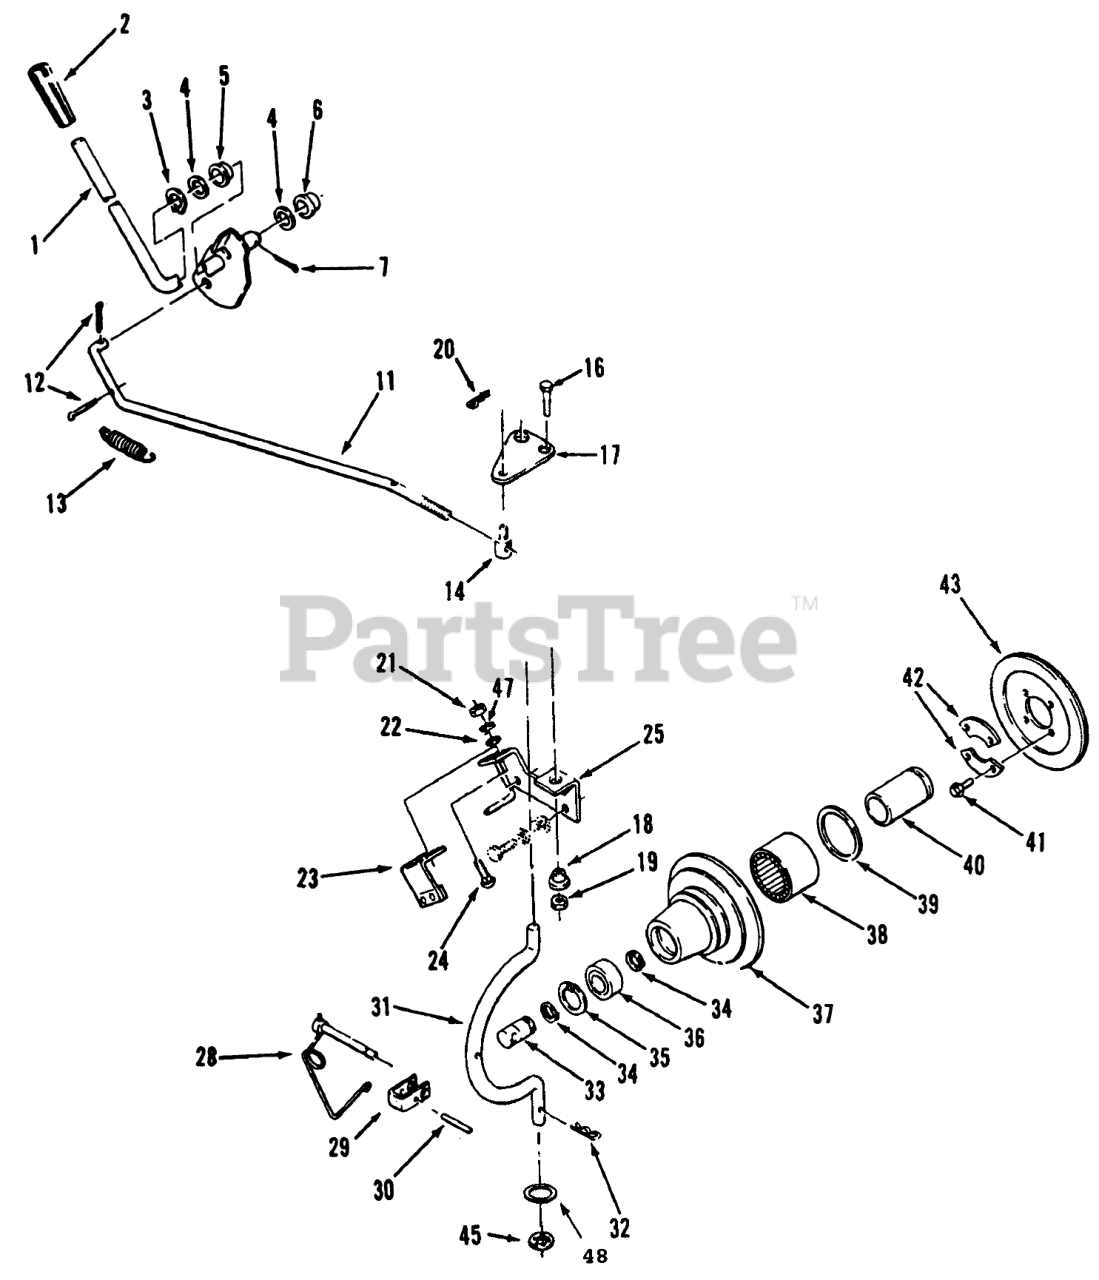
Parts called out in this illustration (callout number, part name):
1	ASSY PTO CLUTCH LEVE
2	GRIP
3	Grip Ring
4	SHIM-WASHER
5	BUSHING-NYLINER
6	NYLINER BUSHING
7	PIN-COTTER
11	ROD-PTO CLUTCH
12	PIN-COTTER
13	SPRING
14	TRUNNION
16	SCREW-HH
17	PLATE
18	SPACER-LIFT LINK
19	NUT-LOCK, NI
20	Hairpin Cotter
21	NUT-JAM
22	WASHER-FLAT
23	ASM-Bracket
24	SCREW-CARR
25	Bracket
28	LOCKING PIN ASM
29	CLEVIS
31	ROD-HOUSING
32	Hairpin
33	SHAFT-PTO
34	Ring-Snap
35	Ring-Snap
36	BEARING-BALL
37	Housing-Clutch
38	BRG-NEEDLE OPEN END
39	Seal
40	RACE-BEARING
41	SCREW-HH
42	RETAINER
43	Facing-Clutch
45	RING-REINFORCED CIRC
47	WASHER-LOCK
48	Washer-Flat
